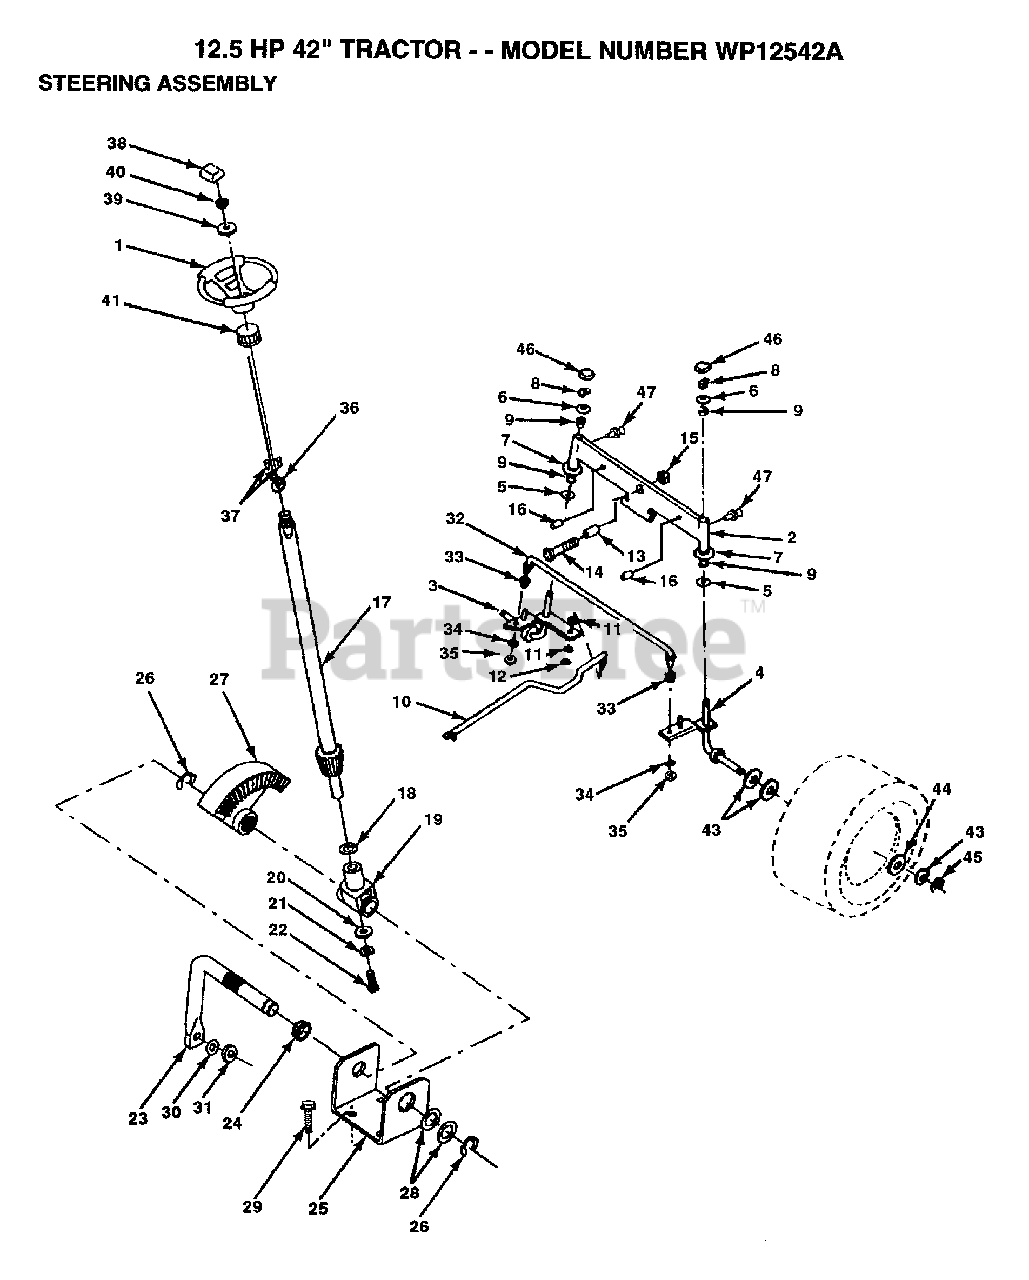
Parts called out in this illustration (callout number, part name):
3	SPINDLE LH
4	SPINDLE RH
5	WASHER .T
6	WASHER
7	WASHER
8	RING
9	COL. SRTG. BEAR.
11	LOCKWASHER
13	BEARING
14	BOLT HEX 5/8-11
16	AXLE PIN
17	STEERING SHAFT
18	THRUST WASHER
19	SUPPORT.SHAFT
21	LOCKWASHER
22	"SCREW,SPECIAL"
24	NYLINER T
25	"BRKT,STEERING"
26	RING
28	WASHER .T
29	SCREW
30	LOCKWASHER
32	TIE ROD
33	WASHER M
35	LOCKWASHER
36	NUT.LOCK.5/16-24
38	"INSERT,STR WHEEL"
39	WASHER
41	ADAPTER LT
43	WASHER
44	WASHER
45	RING
46	CAP
47	ZERK M
